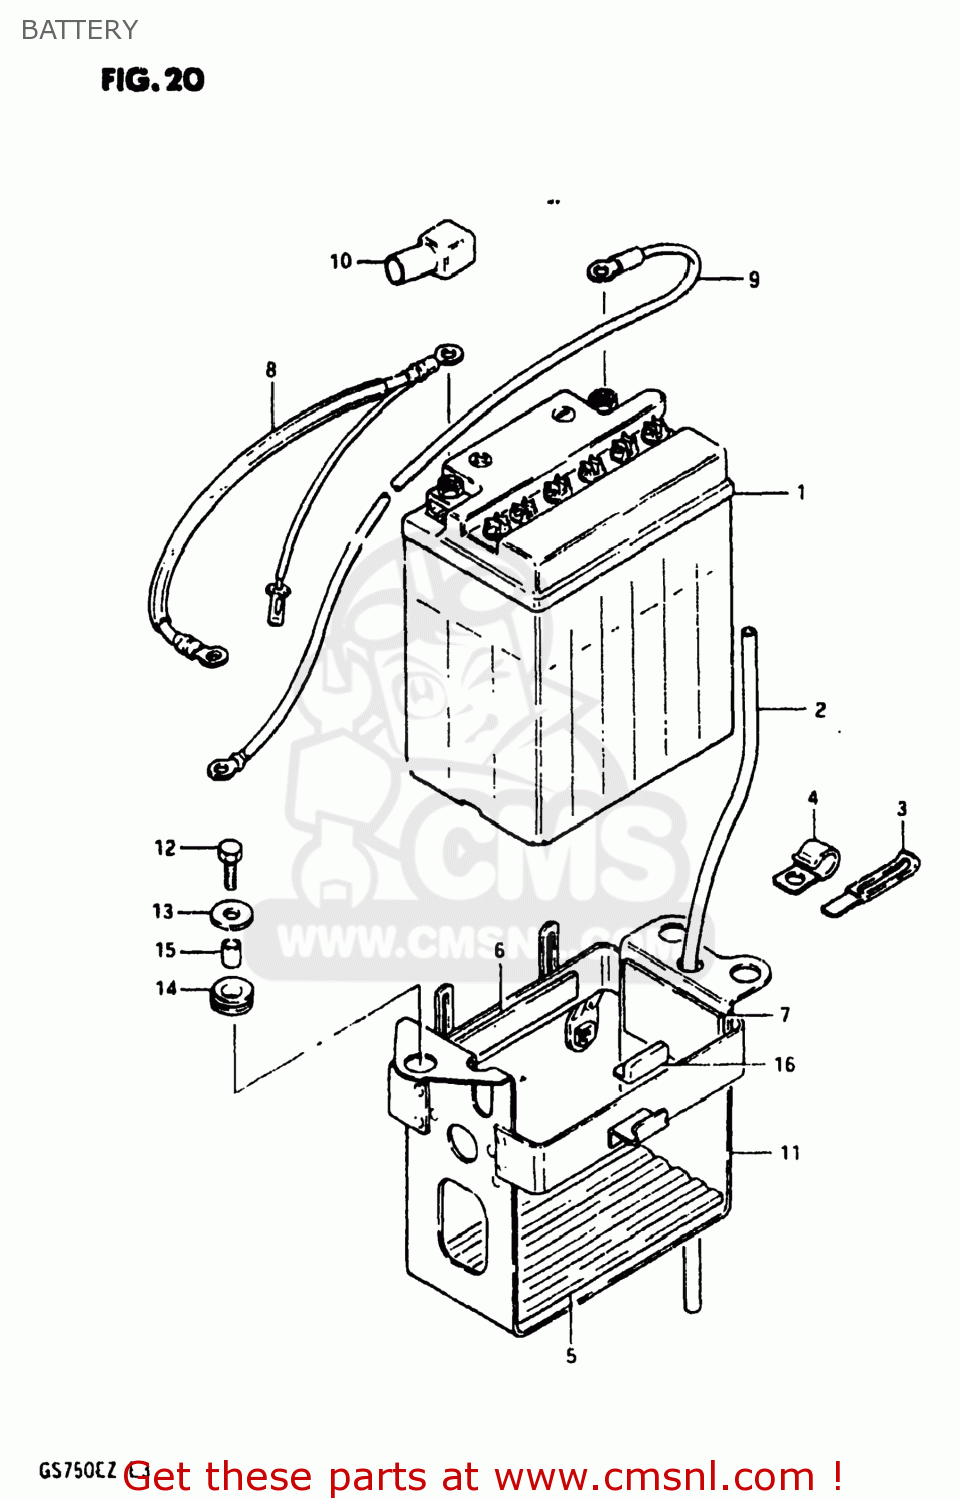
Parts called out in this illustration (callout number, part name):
1	BATTERY ASSY (12V)
2	HOSE,BATTERY EXHAUST
3	CLAMP L:35
4	CLAMP
5	PROTECTOR,BATTERY
6	PROTECTOR(20X90)X4
7	PROTECTOR,BATTERY
8	WIRE,BATTERY PLUS
9	LEAD WIRE,BATTERY(-)
10	CAP,TERMINAL
11	HOLDER,BATTERY
12	BOLT, UPPER
13	WASHER
14	CUSHION
15	SPACER(6.1X9X7.5)
16	CUSHION,FRAME COVER
